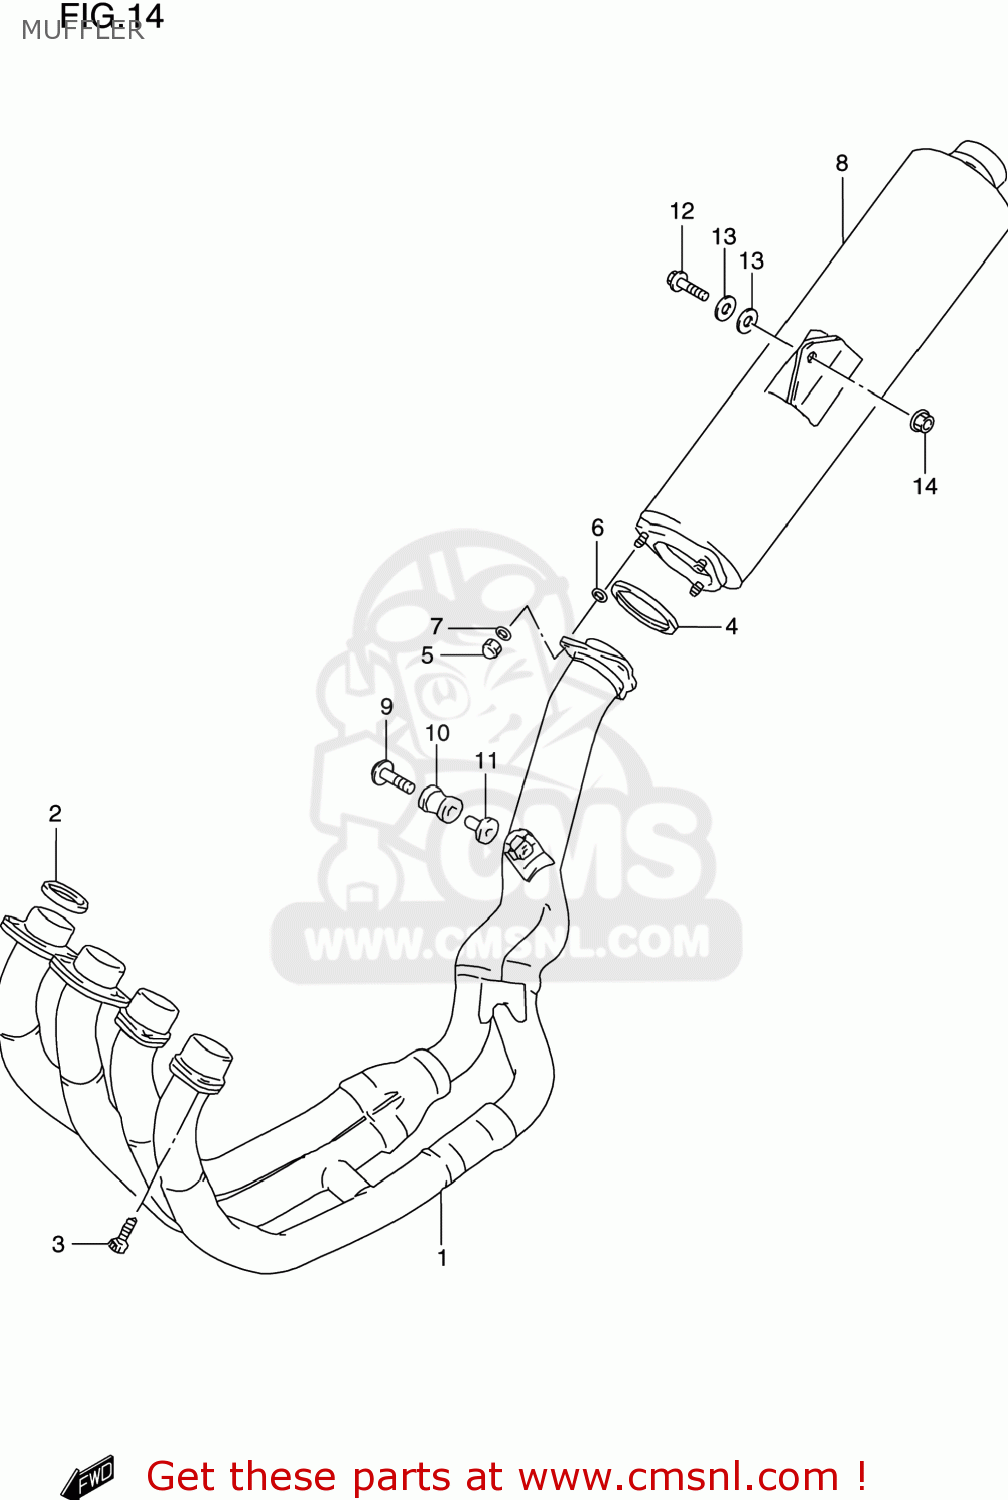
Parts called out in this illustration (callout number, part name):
1	EXHAUST
2	GASKET,EXHAUST PIPE
3	BOLT
4	GASKET,MUFFLER JOINT
5	NUT
6	WASHER(8.5X18X1.6)
7	O RING(D:1.9,ID:7.8)
8	BODY,MUFFLER
9	BOLT 8X45
10	CUSHION
11	SPACER(8.6X12X24.2)
12	BOLT
13	WASHER (8.2X24X1.6)
14	NUT
